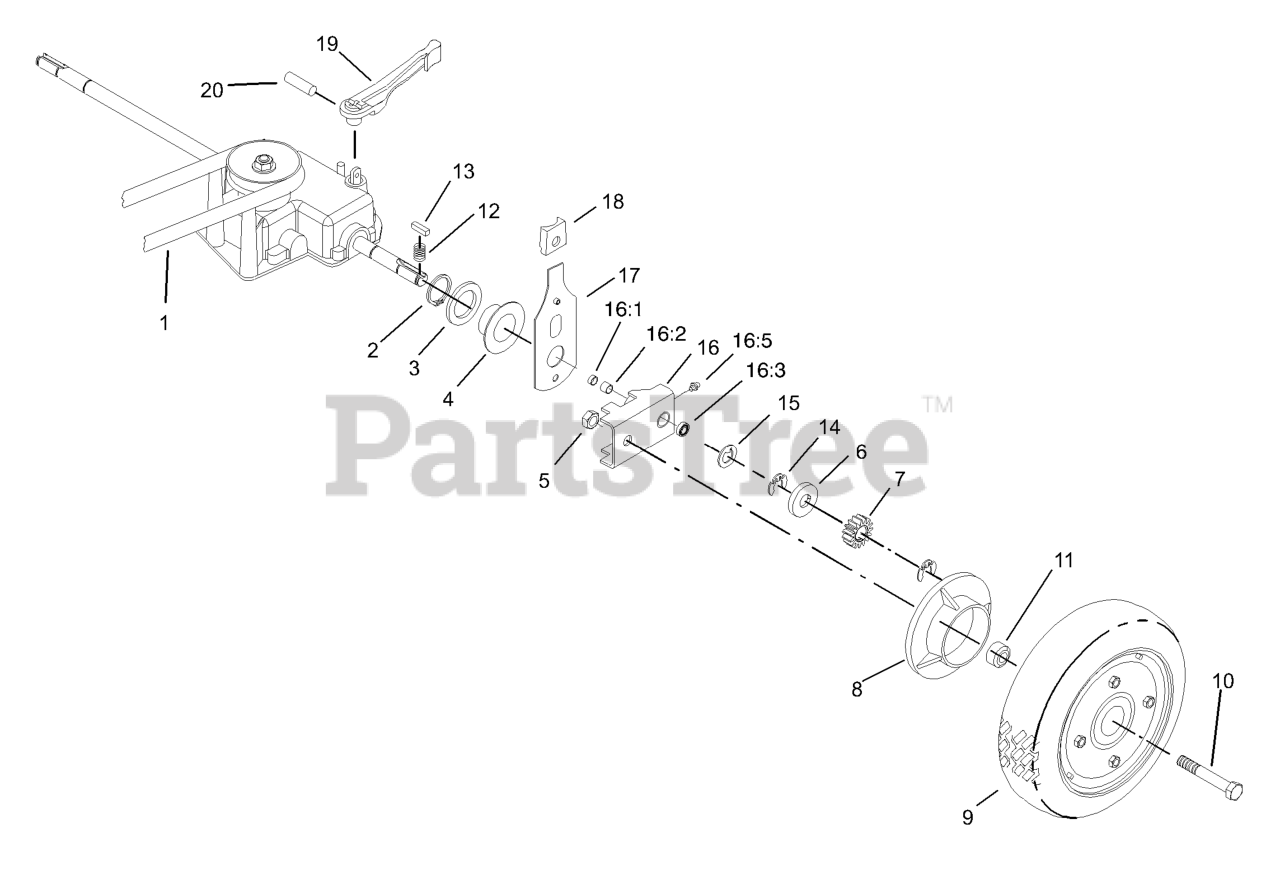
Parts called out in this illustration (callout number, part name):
1	V-BELT
2	RING-RETAINING
4	CAP-END
5	NUT-LOCK, CONE
6	WASHER-THRUST, OUTER
7	GEAR-PINION
8	COVER-WHEEL
10	SCREW-HH
11	SPACER-COVER, WHEEL
12	SPRING-COMPRESSION
14	RING-RETAINING
15	WASHER-THRUST, OUTER
16	PIVOT ARM ASM
16:1	SEAL-OIL
16:3	BEARING-WHEEL
17	REAR SPRING ARM ASM
18	KNOB-ARM
19	LEVER-SHIFT
20	PIN-SPRING
